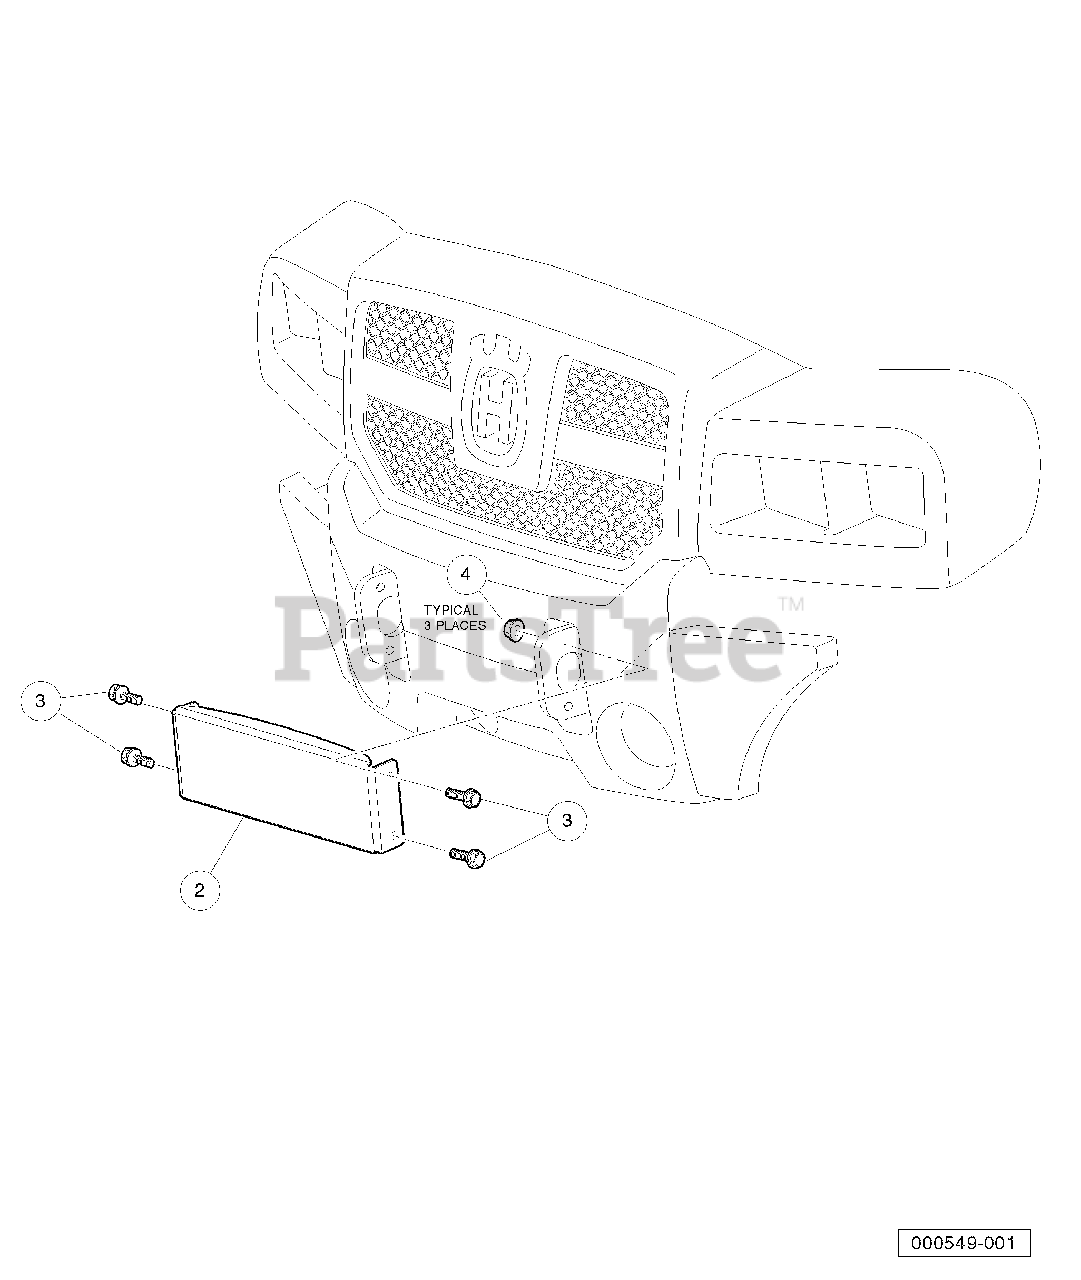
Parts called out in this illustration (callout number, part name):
1	Instl, Bumper Plate, Huv
2	Bumper Plate, Huv
3	Screw, M10 X 1.25 X 30 Hex Blk
4	Nut, Flg, M10 X 1.25 Hex Blk
